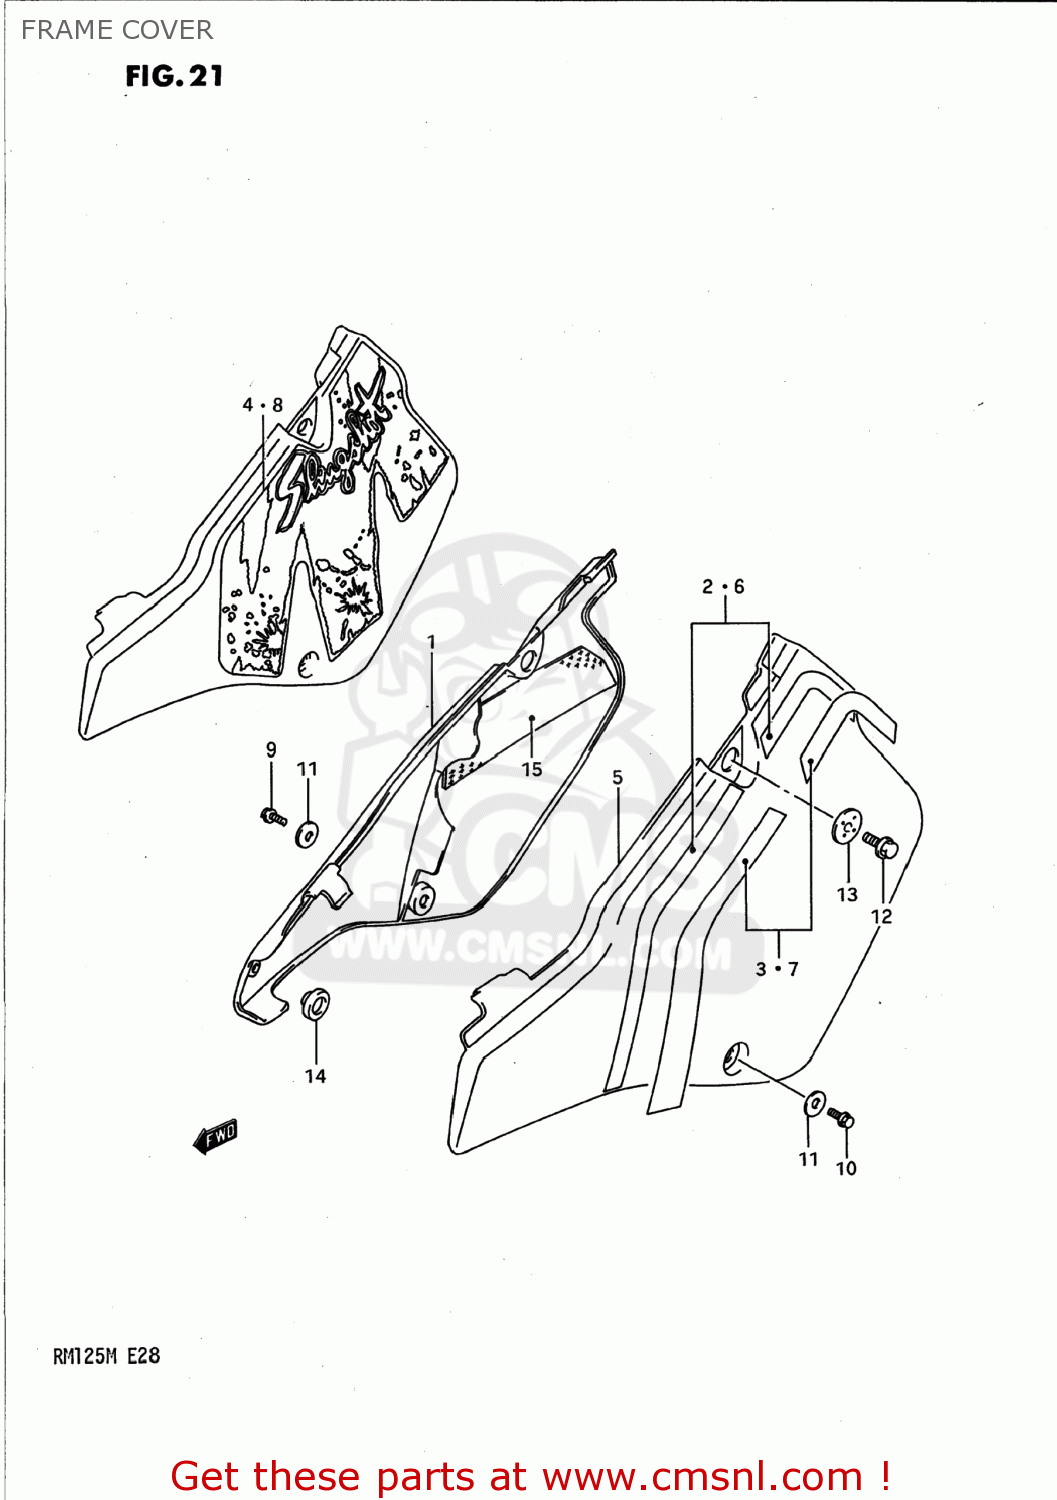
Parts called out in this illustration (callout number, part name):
1	COVER,FRAME,RIGHT
2	EMBLEM
3	TAPE SET,FRAME COVER,RIGHT (B
4	TAPE SET,FRAME COVER NO
5	COVER,FRAME,L(WHITE)
6	EMBLEM,FRAME COVER
7	TAPE SET,FRAME COVER,LEFT (B
8	TAPE SET,FRAME COVER NO
9	BOLT
10	BOLT
11	GASKET(6.5X20X1.5) (NAS)
12	BOLT
13	WASHER
14	CUSHION
15	SHIELD,FRAME COVER,RIGHT
